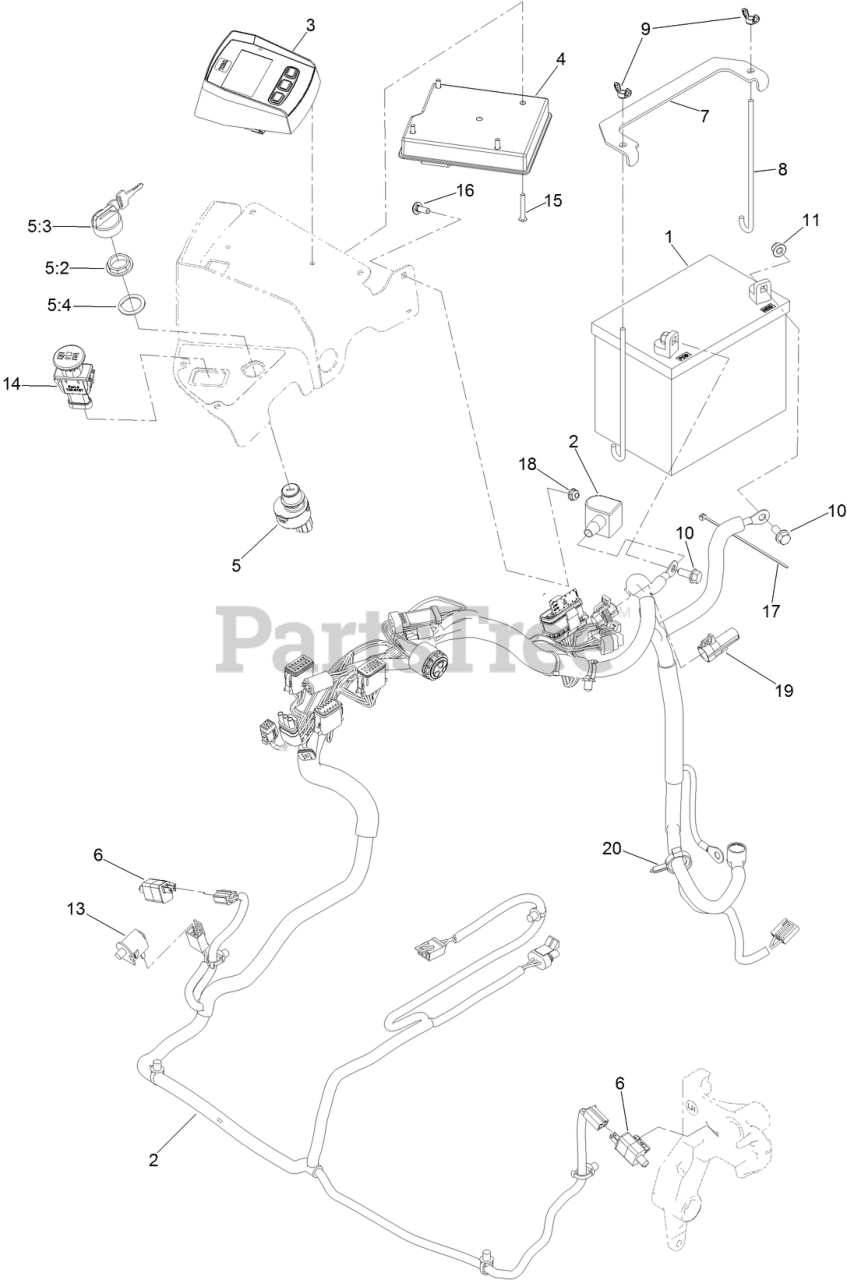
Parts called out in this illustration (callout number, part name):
1	BATTERY-DRY
2	HARNESS-WIRE
3	MODULE-HORIZON
4	MODULE-MCU
5	IGNITION SWITCH ASM
5:2	NUT-MOUNTING
5:3	IGNITION KEY SET
5:4	WASHER-BACKUP
6	SWITCH
7	STRAP-TIE DOWN, BATTERY
8	BOLT-HOLDDOWN
9	WINGNUT
10	SCREW-HHF
11	NUT-HF, NI
13	SWITCH-BAIL
14	SWITCH-PTO, SEALED
15	SCREW-PPH
16	BOLT-CARR
17	TIE-CABLE
18	NUT-HF
19	COVER-CONNECTOR, MP150, 4M
20	CLAMP-HOSE
